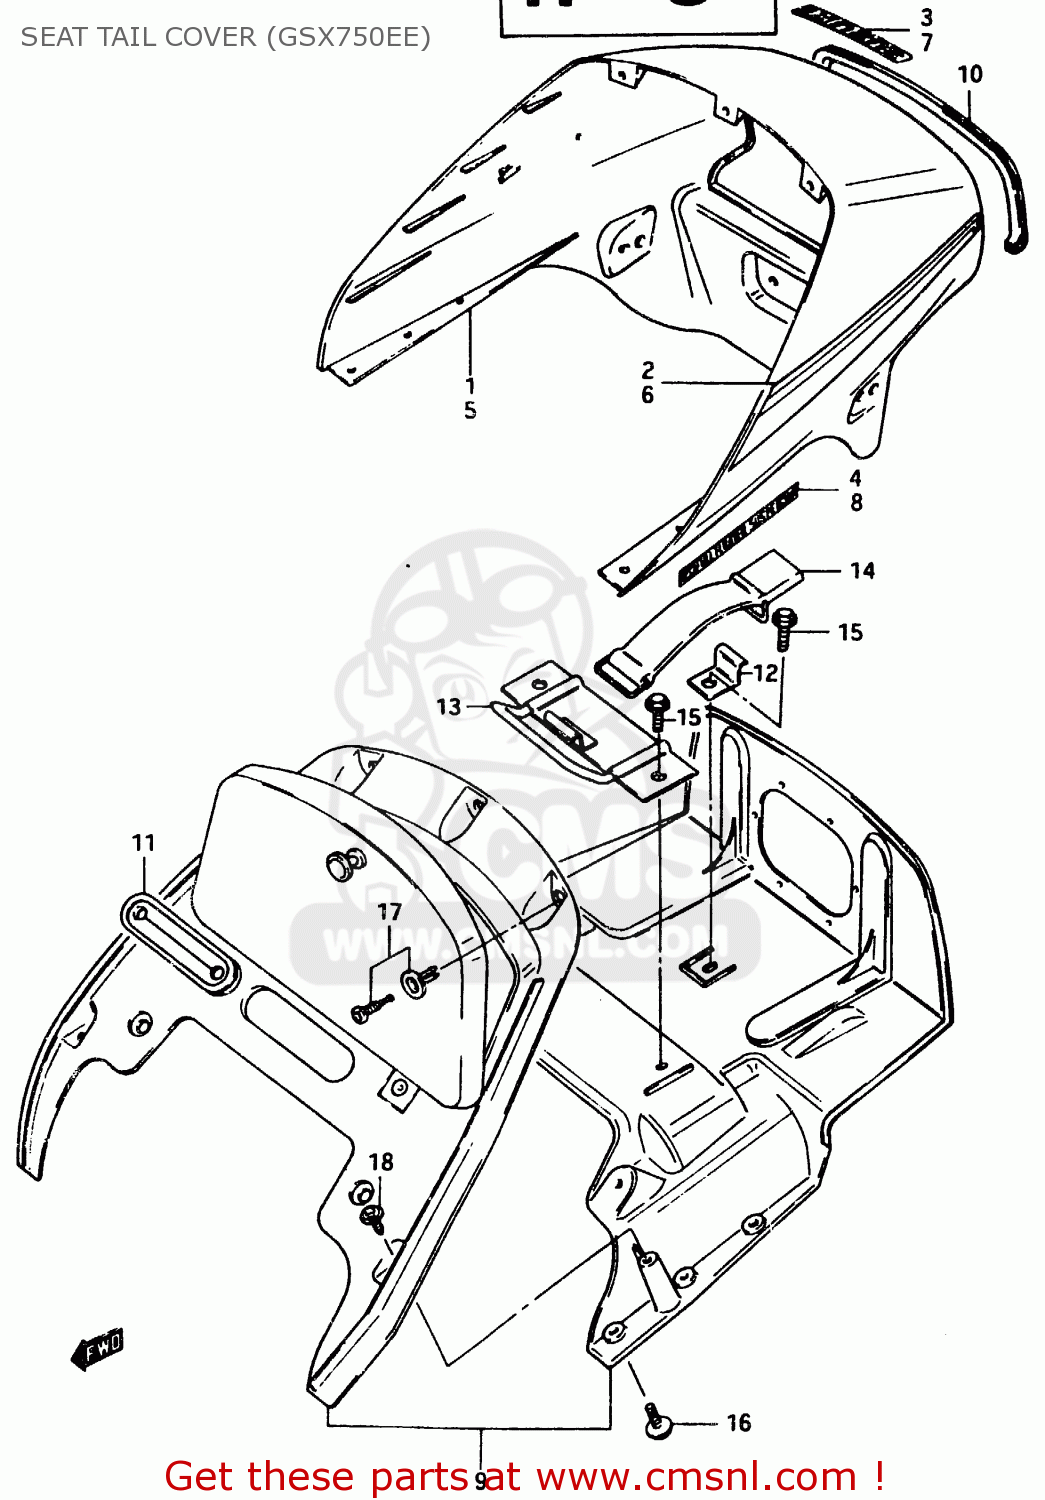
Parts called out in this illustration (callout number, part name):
1	TAIL COVER, SEAT (BLUE)
2	TAPE SET, SEAT TAIL COVER
3	EMBLEM(WHITE)
4	EMBLEM
5	TAIL COVER, SEAT (RED)
6	TAPE SET, SEAT TAIL COVER
7	EMBLEM(WHITE)
8	EMBLEM
9	FLAP,SEAT TAIL COVER
10	MOLDING,SEAT TAIL COVER
11	GROMMET,SEAT TAIL COVER
12	PLATE,CHAIN LOCK HOLDER
13	PLATE,SEAT HOOK
14	BAND
15	BOLT
16	SCREW
17	CLIP
18	SCREW
